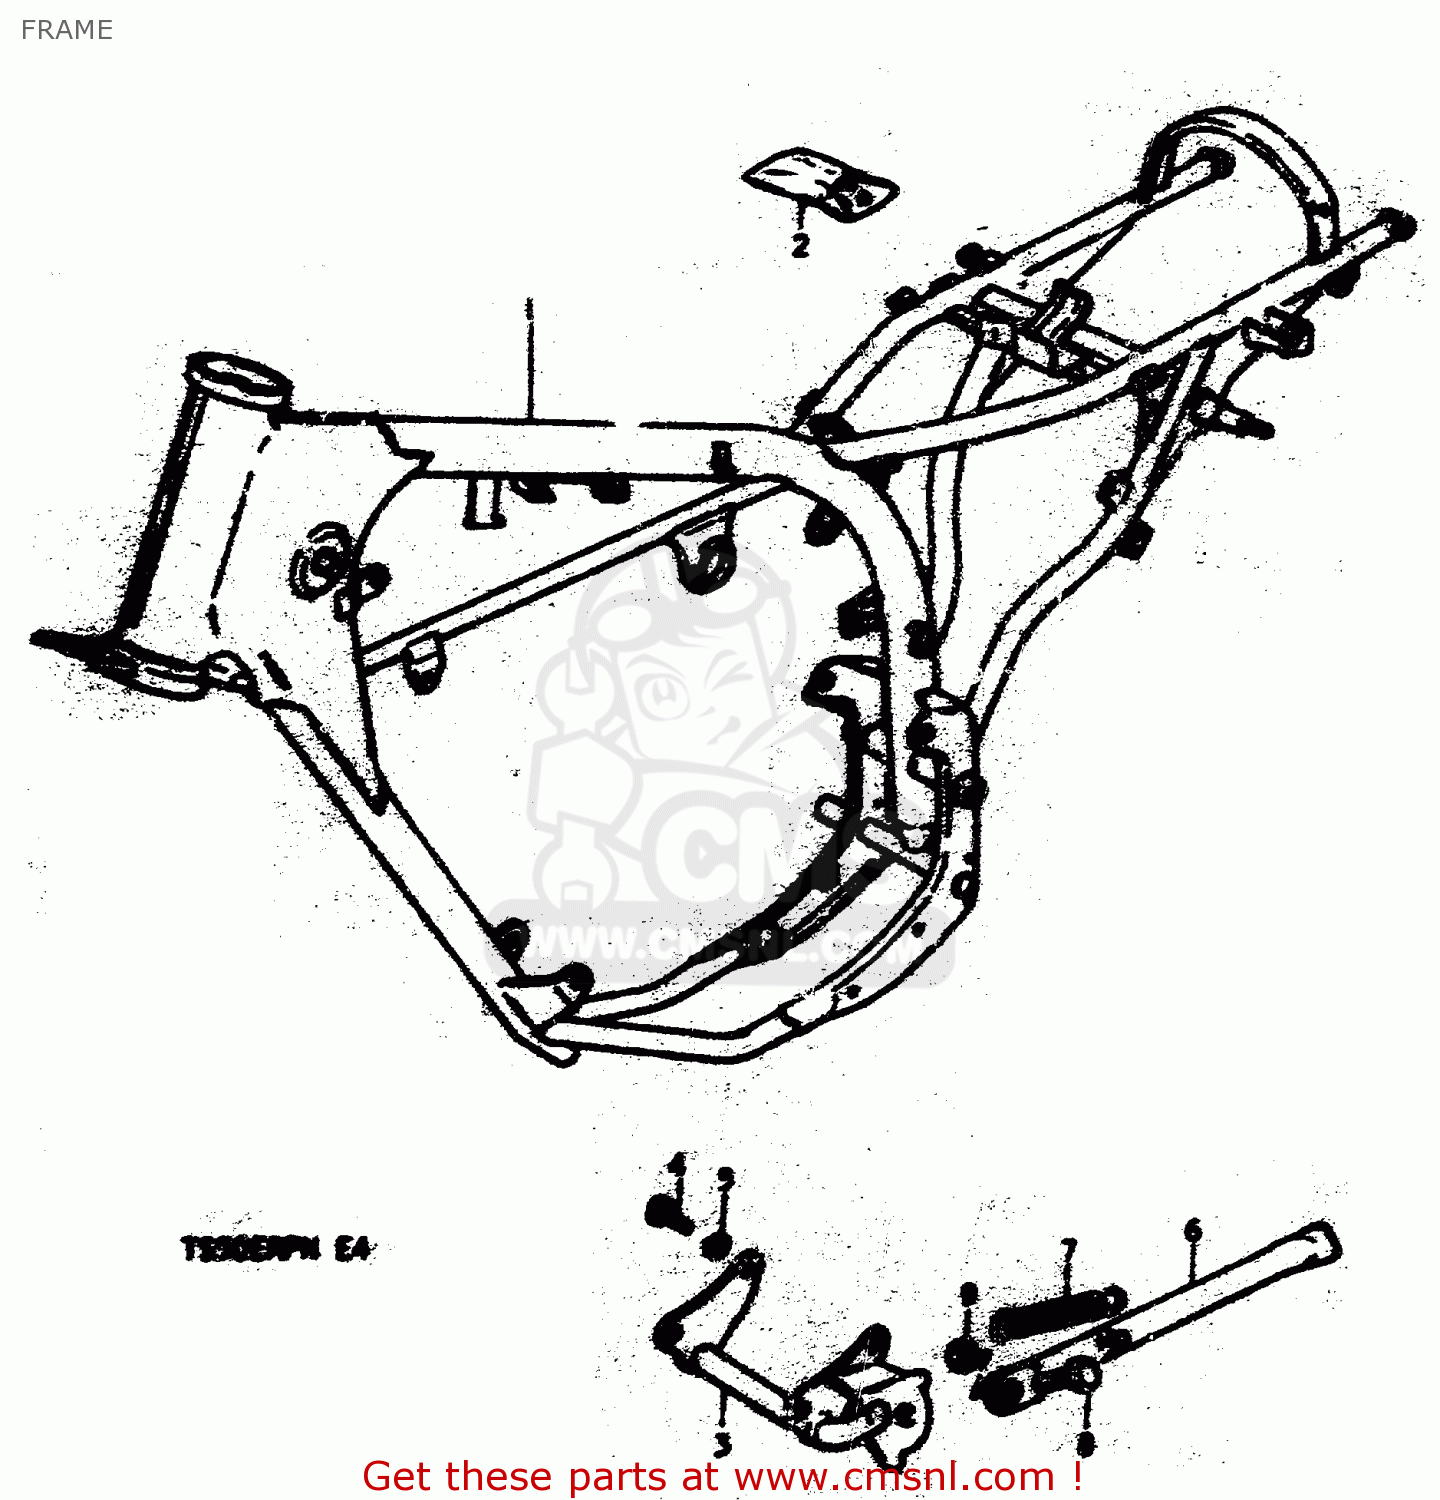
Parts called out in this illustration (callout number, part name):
1	FRAME (BLACK)
2	TOOL SET
3	BAR, FRONT FOOTREST
4	BOLT
5	LOCK WASHER
6	STAND, PROP
7	SPRING
8	BOLT
9	NUT
